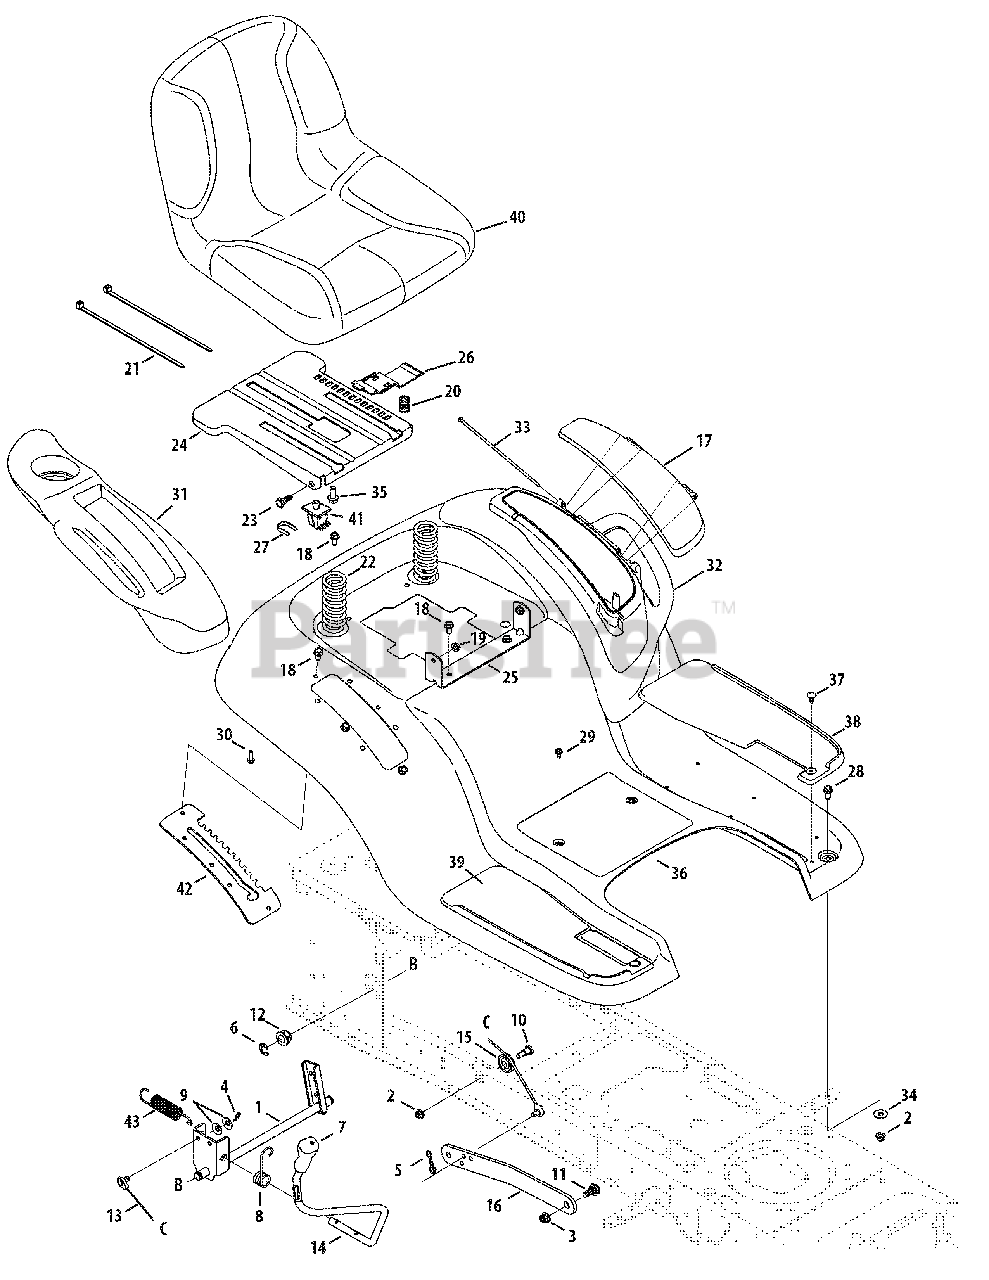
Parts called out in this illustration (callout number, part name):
1	Shaft Ass’y, Lift
2	Nut, Flange Lock, 5/16-18, Grf
3	Nut, Flange Lock, 3/8-16, Grf
4	Pin, Cotter, .072 Dia. x 1.13
5	Pin, Cotter, Bow-Tie 72
6	Ring, E Type, .625 Dia. Shaft
7	Grip, Handle, Cub, .50 ID
8	Spring, Torsion
9	Washer, Spring, .401 x .870 x .063
10	Screw, Shoulder, .437 x .470, 5/16-18
11	Bolt, Shoulder, .50, 3/8-16
12	Bearing, Hex Flange
13	Cable, Lift, 16.16
14	Handle, Lift,
15	Pulley, Roller, Cable
17	Door, Cover, Fender
18	Screw, Self-tapping, 5/16-18, .750,
19	Nut, Flange Lock, 5/16-18, Gr5, Sd Lk
20	Spring, Compression, .68 x 1.065 x .055
21	Cable, Tie, 3/16 x .05 x 7.4
22	Spring, Compression, 1.71 x 3.735 x .238
23	Screw, Shoulder, .437 x .268, 5/16-18
24	Bracket, Mounting, Seat
25	Bracket, Pivot, Seat
26	Lever, Seat Adjustment
27	Clip, Retaining, Switch
28	Hex Screw, 5/16-18, .75, Gr5, Std
29	Screw, Self-tapping, 1/4-20, 0.500,
30	Screw, HL, 1/4-15, 0.750,
31	Cover, Fender, RH
32	Cover, Fender, LH
34	Washer, Flat .344 x 1.00 x .063
35	Hex Flange Screw, 3/8/16, .875, Gr5
36	Fender, Cub Hydro
37	Clip, Ratchet, .250 Dia
38	Pad, Foot, LH
39	Pad, Foot, RH
40	Seat, High Back Cloth, Cub
41	Switch, Seat
42	Bracket, Lift
43	Spring, Extension, 1.15 OD x 5.99
